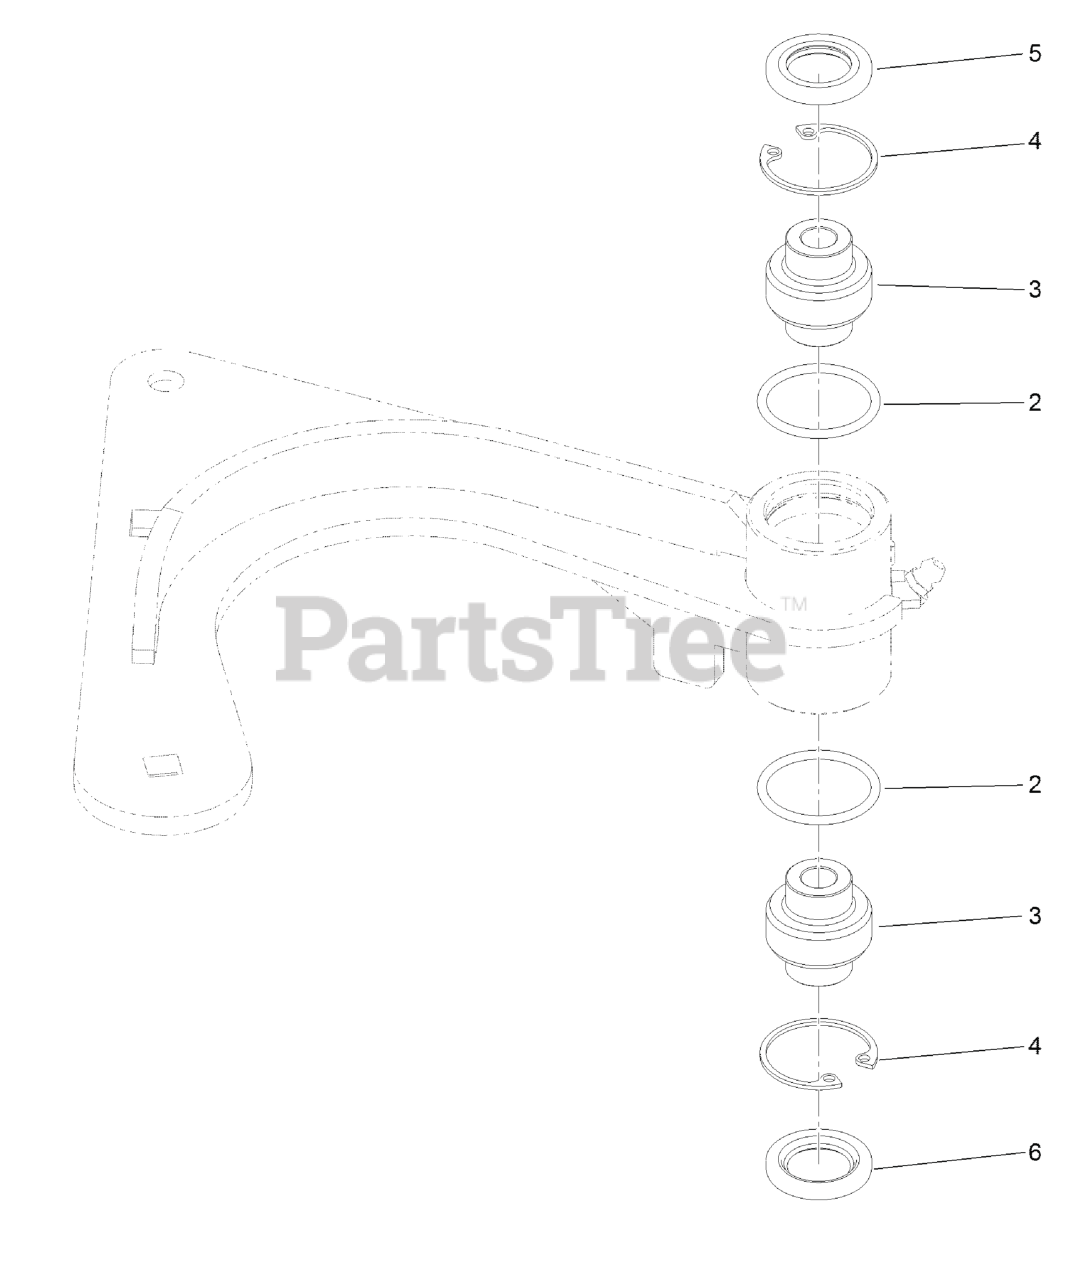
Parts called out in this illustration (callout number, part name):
3	BEARING-SPHERICAL
4	RING-SNAP
5	SEAL-LIP, DOUBLE
6	SEAL-LIP, SINGLE
